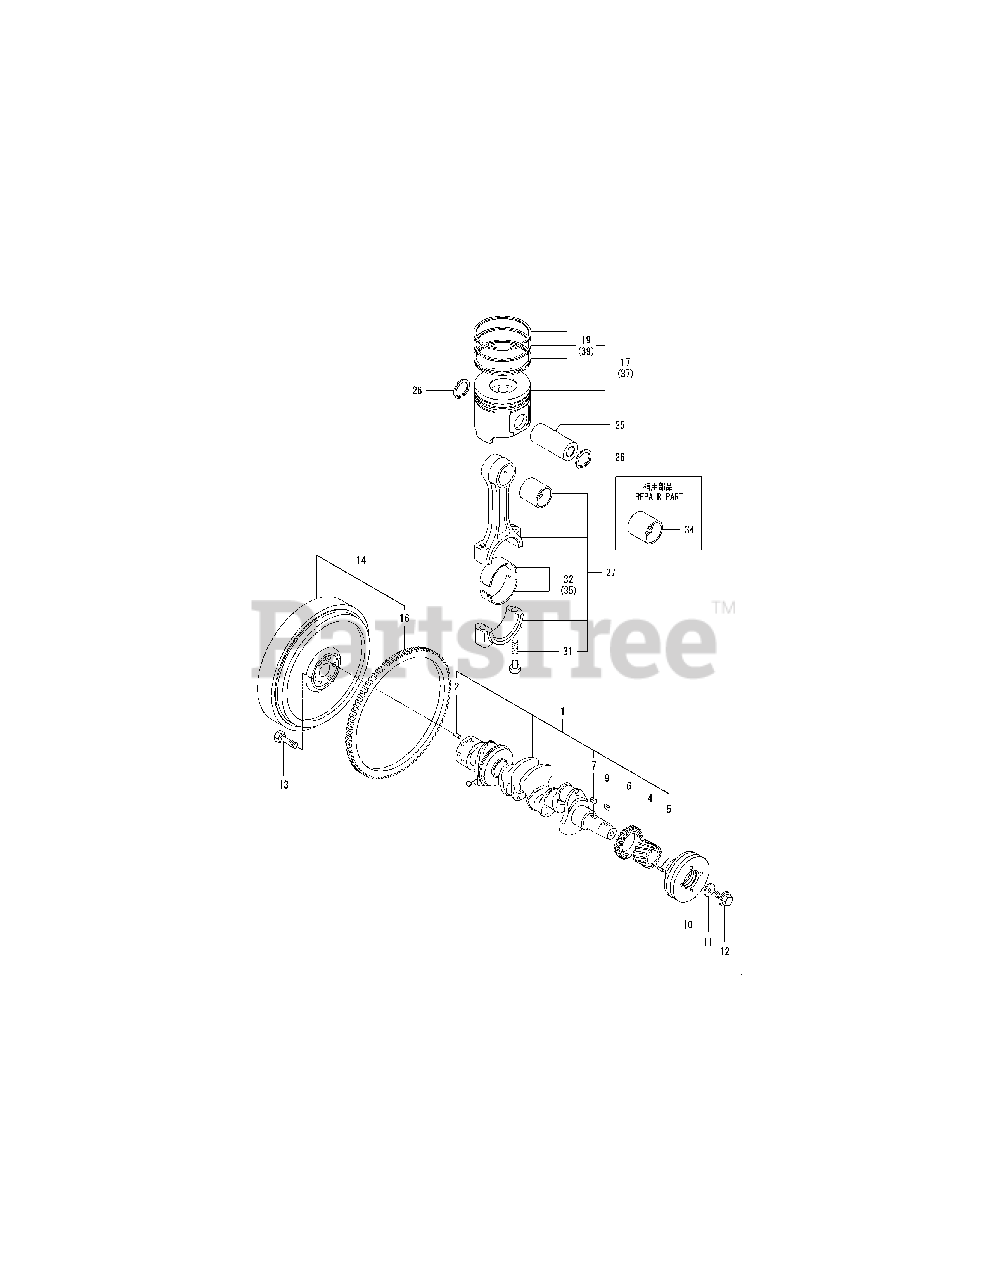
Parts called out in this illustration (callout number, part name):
1	CRANKSHAFT ASSY
4	GEAR, CRANKSHAFT
6	GEAR, BALANCER
10	V-PULLEY, CRANKSHAFT
12	BOLT, V-PULLEY
13	BOLT, FLYWHEEL
17	PISTON W/RINGS
19	RING SET, PISTON
25	PIN, PISTON (D26,L70)
27	ROD ASSY, CONNECTING
31	BOLT, CONNECTING ROD
32	METAL, CRANKPIN
34	METAL, PISTON PIN
35	METAL.PIN US=0.25
37	PISTON W/RINGS OS.25
39	RING SET, PISTON .25
